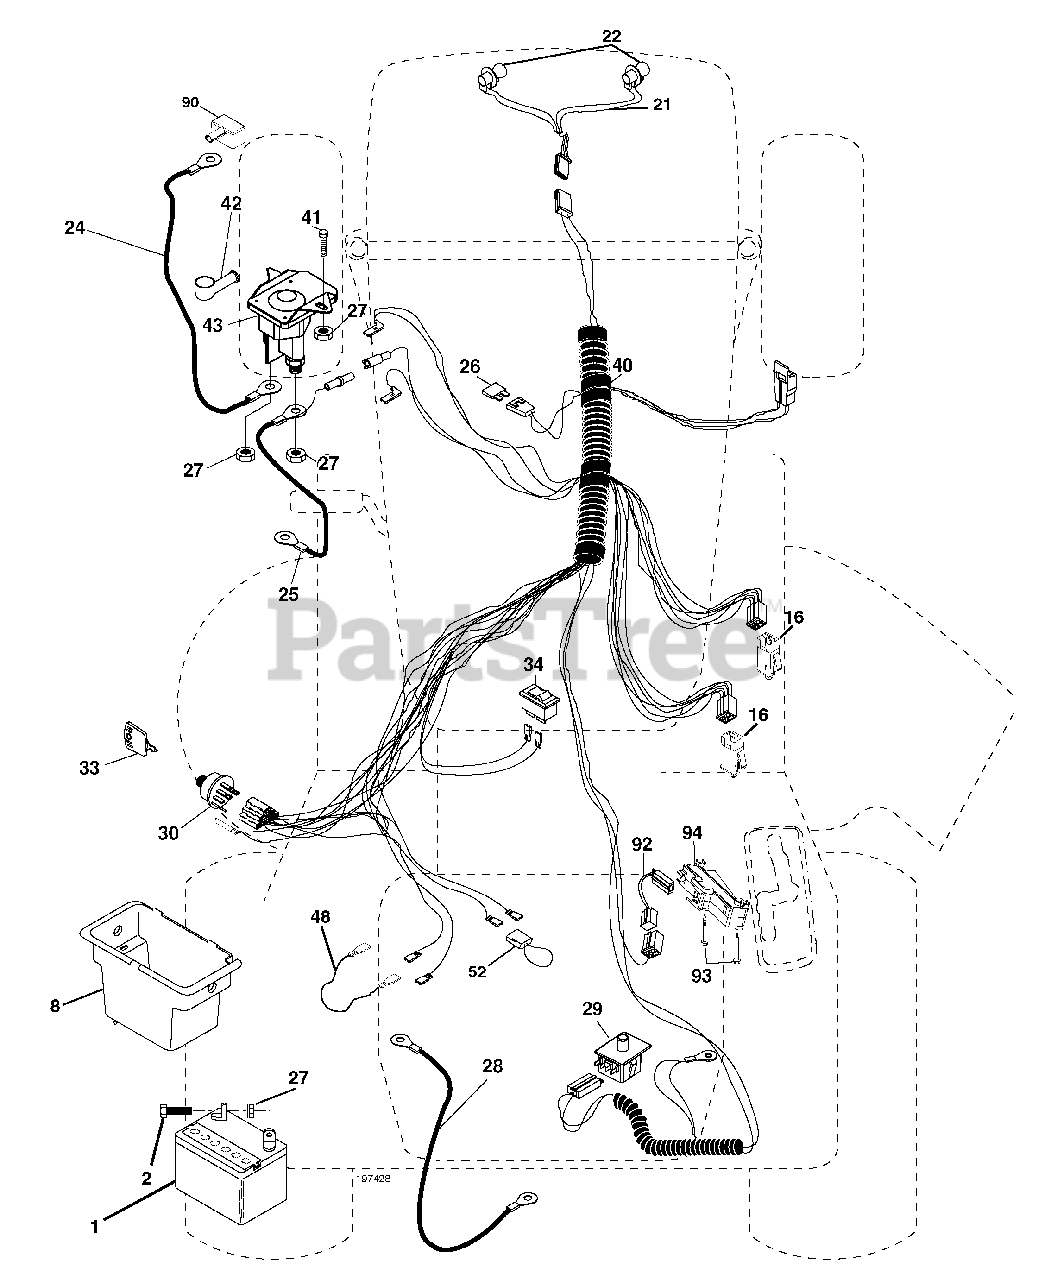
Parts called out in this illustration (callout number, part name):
1	Battery
2	Bolt Hex Hd 1/4-20 unc x 3/4
8	Box Battery
16	Switch Interlock
21	Harness Asm Light W/4152j
22	Bulb Light #1156
24	Cable Battery 6 Ga. 11"red
25	Cable Battery
26	Fuse 20 AMP
27	Nut Keps Hex 1/4-20 unc
28	Cable Ground 6 Ga. 12" Black
29	Switch Seat
30	Switch Ign
33	Key Ign
34	Switch Light/Reset
40	Harness Ign
41	Bolt Blk Fin Hex 1/4-20
42	Cover Terminal Red
43	Solenoid
48	Adapter Ammeter
52	Protection Wire Loop
90	Cover Terminal Battery
92	Harness Pigtail
93	Screw Plastite 10-14 x 2.0
94	Module Reverse ROS
